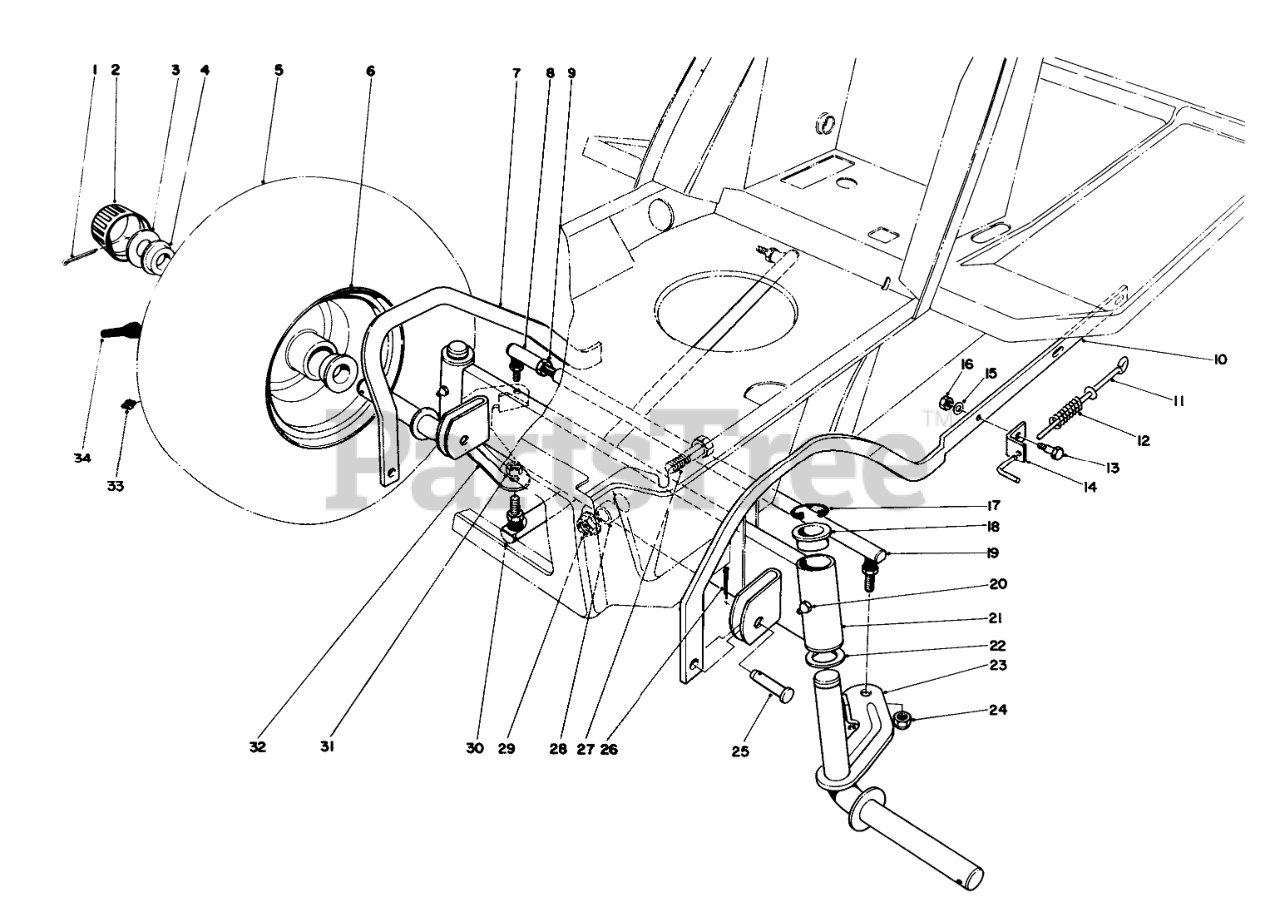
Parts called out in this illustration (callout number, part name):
1	PIN-COTTER
2	CAP-HUB
3	WASHER-PLAIN
4	Bearing
5	FRONT TIRE
6	FRONT RIM
7	Scissors Link-R.H.
8	JOINT-BALL
9	NUT-JAM
10	Scissors Link-L.H.
11	Pin-Tension
12	COMP SPRING
13	Bolt-Shoulder
14	TENSION BELT BRKT B
15	WASHER-PLAIN
16	NUT-LOCK, CONE
17	E-RING
18	BEARING-FLANGE
19	Tie Rod-Steering (Incl. Ref. #8 & 9)
20	GREASE FITTING
21	Front Axle (Incl. Ref. #18)
22	WASHER-THRUST
23	LH SPINDLE WA PP
24	NUT-LOCK, NI
25	PIN-CLEVIS
26	PIN-COTTER
27	SCREW-HH
28	SPACER-AXLE, FRONT
29	NUT-HF
30	STEERING ARM B
31	NUT-HEX
32	RH SPINDLE WA PP
33	FITTING-GREASE
34	STEM-VALVE
